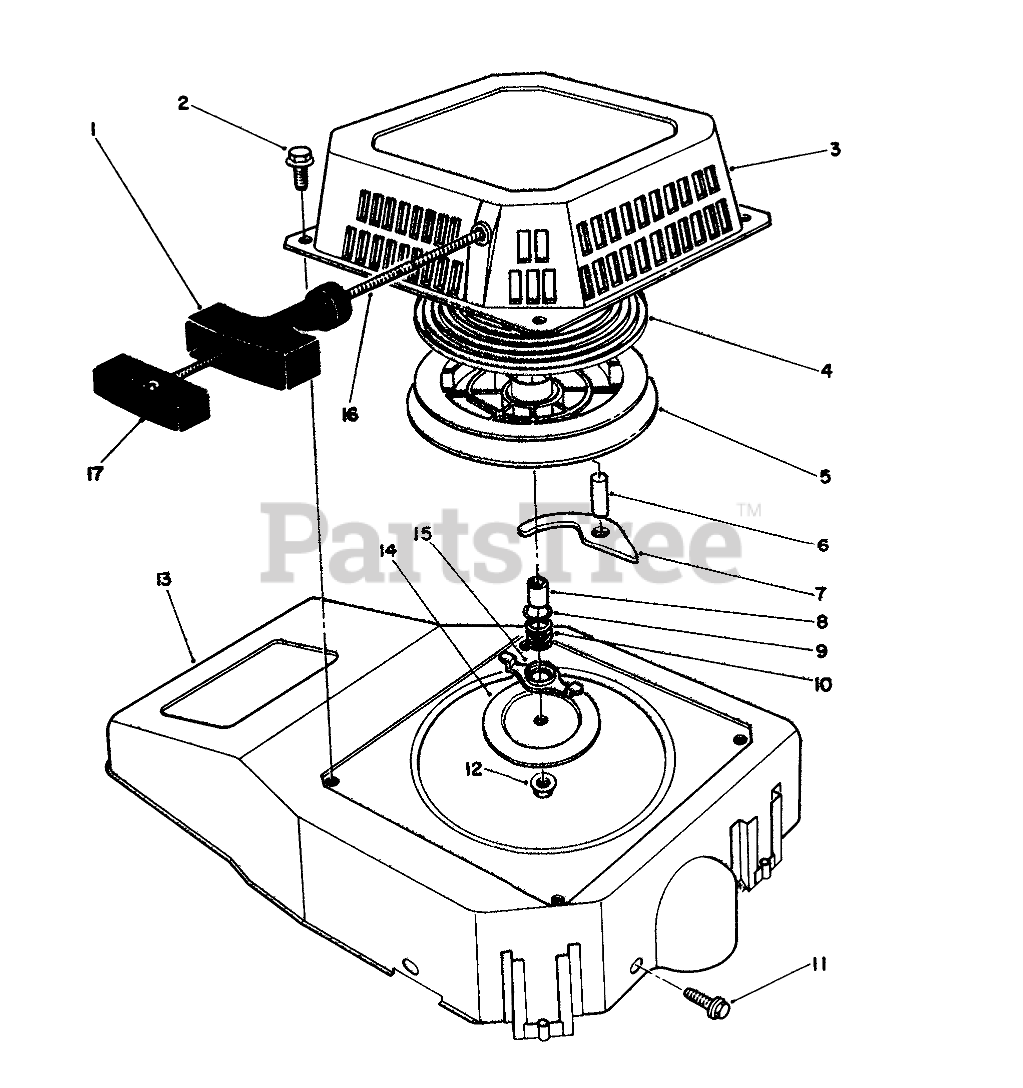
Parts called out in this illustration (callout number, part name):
1	HANDLE
2	SCREW-HHF
3	Case-Recoil
4	SPRING
8	Spacer
9	WASHER
10	Spring-Friction
13	SHROUD
14	PLATE
15	Guide-Paw
16	ROPE-STARTER
17	RETAINER HANDLE
